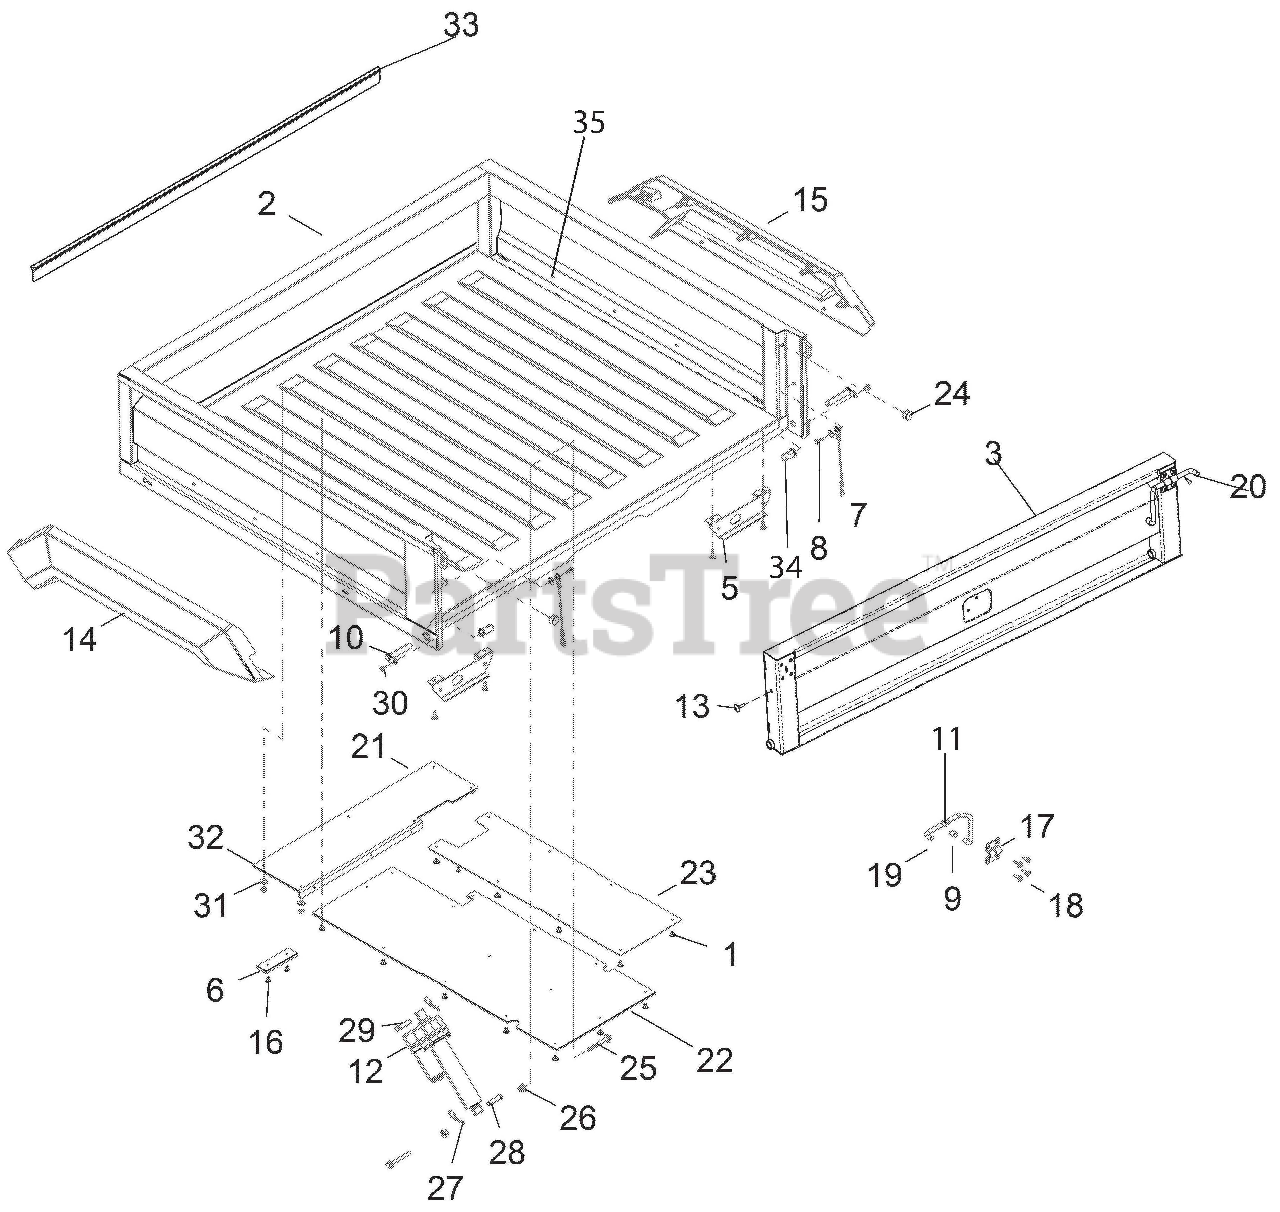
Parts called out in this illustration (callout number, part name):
1	RIVET(50) *
2	BOX, ARNS,GRAVELY RED
3	TAILGATE,ARNS,GRVLY RED
5	BRKT-TAIL LIGHT MOUNT
6	BUMPER-BOX BASE
7	CABLE, TAILGATE
8	BLT-SHLDR .188X.188X.25-20
9	CAP, TAILGATE LATCH
10	PIN-TAILGATE MOUNT
11	BUSHING, TAILGATE LATCH
12	ACTUATOR, BOX LIFT
13	SCR-TXTH-M6X1.0X25 RIE,SHDR
14	ASM-FLARE,BOX,CLIP,LH
15	ASM-FLARE,BOX,CLIP,RH
16	NUT-M6 FLANGE,NYLOK
17	BRKT-TAILGATE LATCH
18	SCR-TXTH-M6X1.0X25 RIE
19	ROD, LATCH, LH
20	ROD, LATCH, RH
21	SHIELD, HEAT, EXHAUST, FRONT
22	SHIELD, HEAT, EXHAUST, REAR
23	SHIELD, HEAT EXHAUST MID
24	BUMPER, TAILGATE
25	SCR-HXFL-M10X1.25X80 8.8 ZOD
26	NUT-M10X1.25,FLG,NYLOC-OLIVE D
27	CLIP, HITCH PIN
28	PIN, CLEVIS
29	PIN, CLEVIS BOX LIFT 2"
30	SCR-M6X1X16 TR/TX-M
31	NUT-M6 FLANGE,NYLOK
33	TRIM,BOX
34	BUSHING, TAILGATE PIVOT PIN
35	SCR-TXPH-#14 X .75 HI-LO RIE
